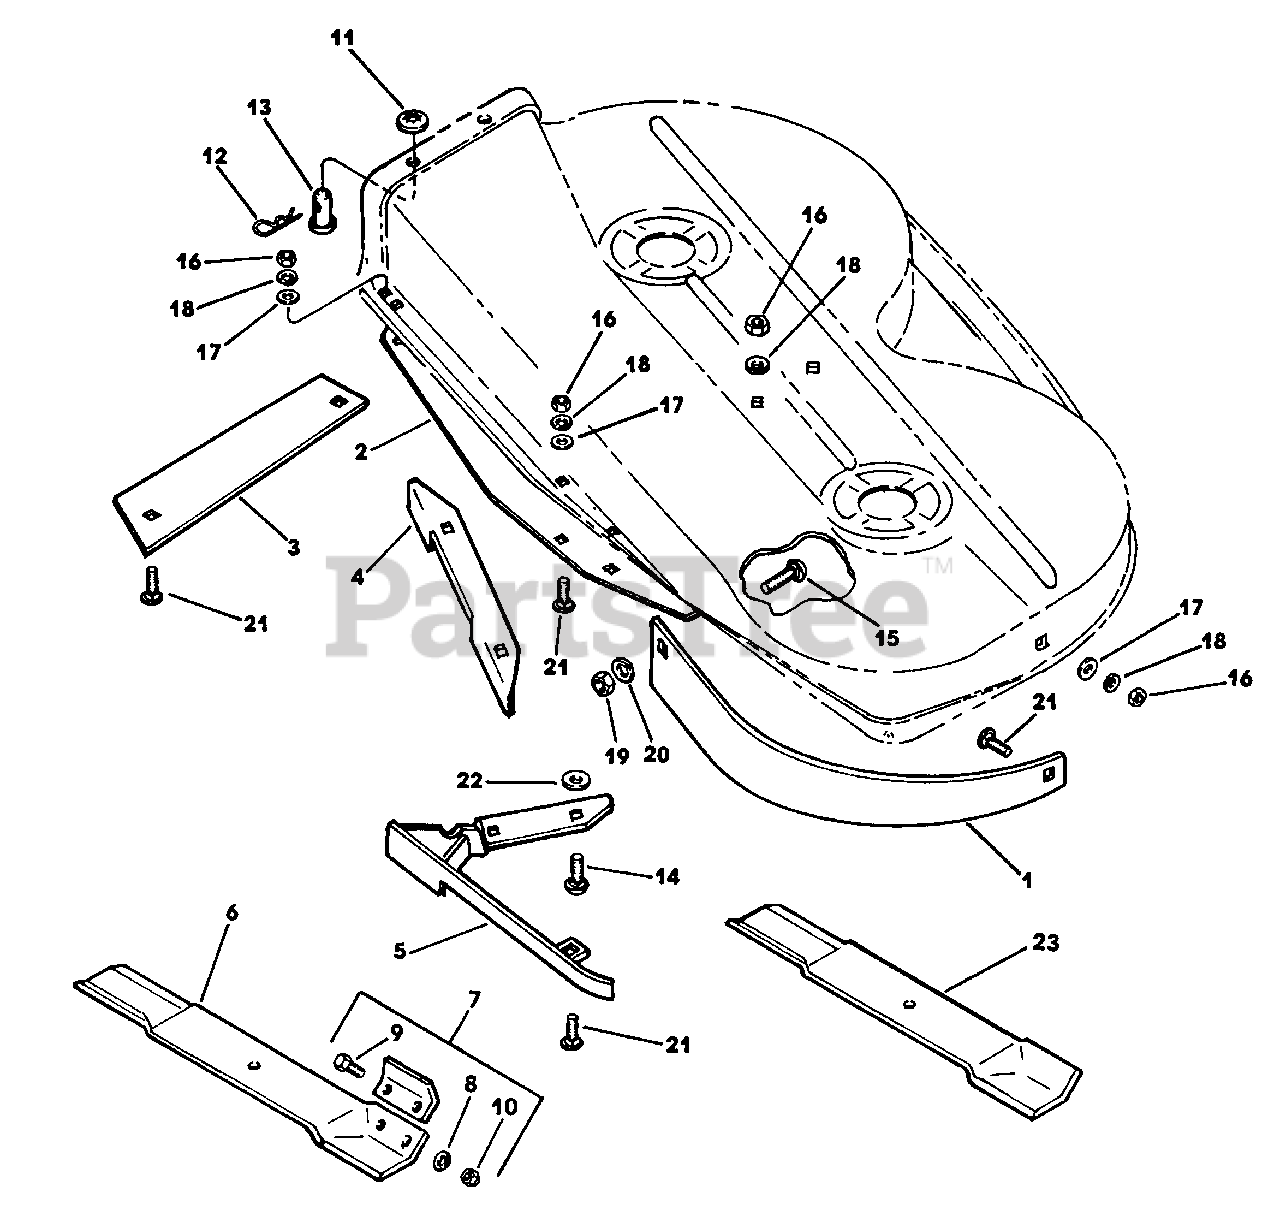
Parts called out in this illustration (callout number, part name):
1	Baffle-L.H
2	Baffle-Front
3	Baffle-R.H
4	Baffle-Discharge
5	Baffle-Center
6	Blade
7	Blade Extension Kit
8	Washer, Saring Lock
9	Cap Screw, Hex Hd
10	Nut, Hex Cone Lock
11	Nut, Push
12	Spring Clip
13	Clevis Pin
14	Carriage Bolt
15	Carriage Bolt
16	Nut, Hex
17	Washer, Flat
18	Washer, Spring Lock
19	Nut, Hex
20	Washer, Spring Lock
21	Bolt, Wafer Hd
22	Washer, Flat
23	Blade
